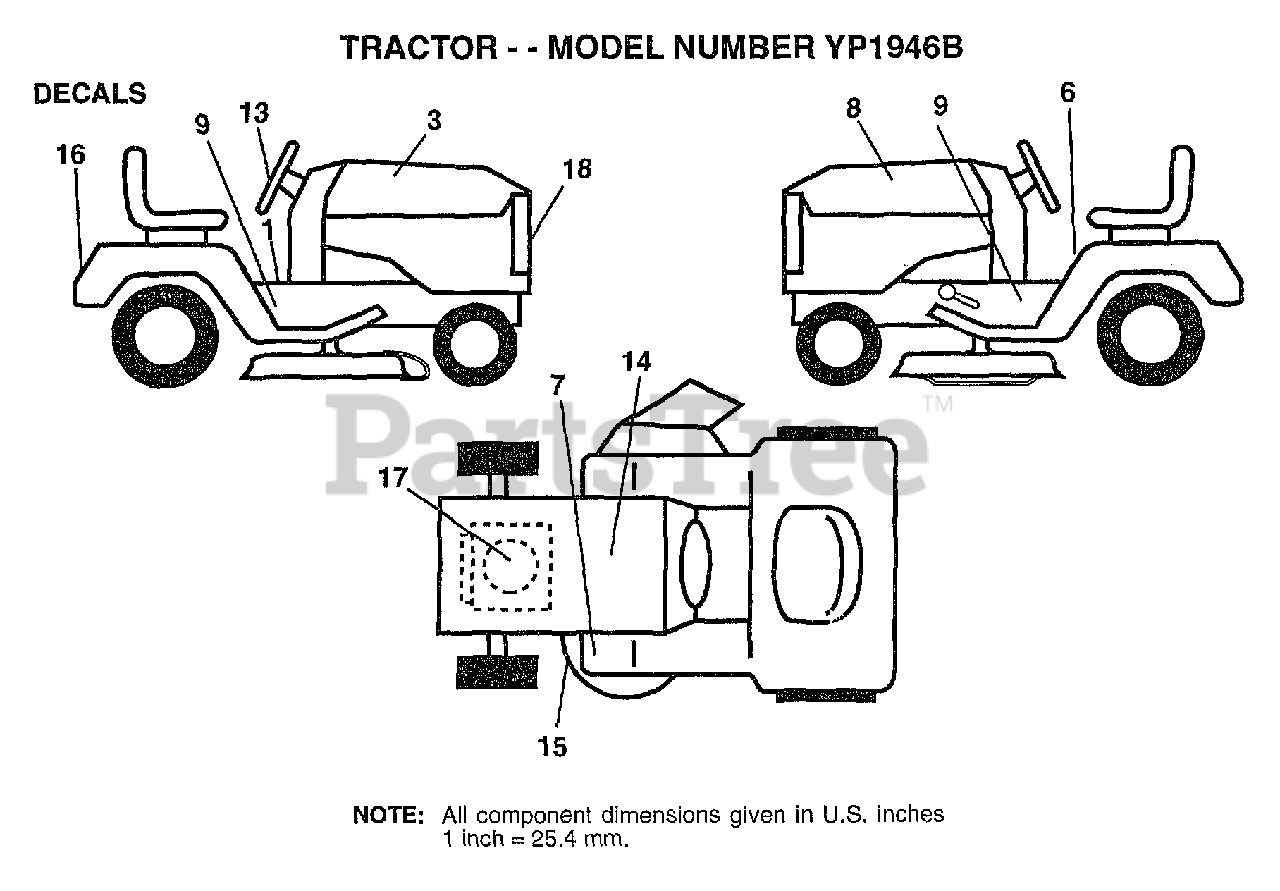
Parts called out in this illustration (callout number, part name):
1	"DECAL DASH,OPER."
3	"DECAL HOOD,RH 19H"
6	"DECAL DANGER,FEND"
9	"DECAL CHASSIS,46"""
13	DECAL INS STRG WH
14	DECAL.BATRY.3-3908
16	DECAL FENDER
17	DECAL, HP ENGINE
